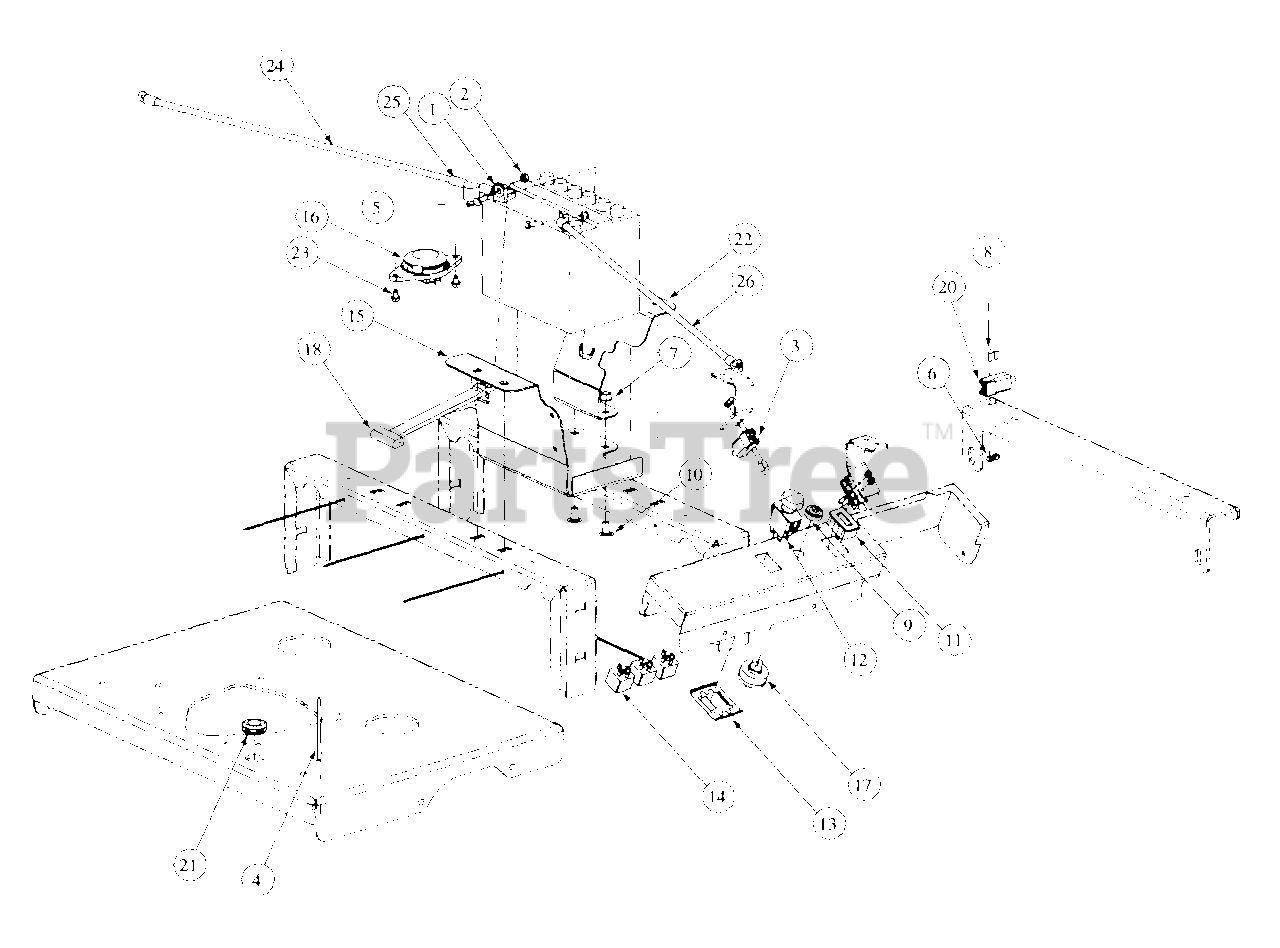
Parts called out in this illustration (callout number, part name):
1	Battery, 12V 225CCA 30 Min
2	Lock Nut, Nylon Insert, 1/4-20
3	Delta Switch
4	Cable Tie, 3/16 x .05 x 7.4
5	HHCS, 1/4-20, .75
6	Lock Nut, Nylon Insert, 10-32
7	Hex Nut, 3/8-16 Flange Lock
8	Phillips Head Screw, Machine, 10-32 x 5/8
9	Nut, W/Cap, 5/8-32 Ignition
10	Carriage Bolt, 3/8-16 x .75 Long
11	Hour Meter
12	Electric PTO Switch
13	Bracket, PTO Retainer Switch
14	Relay, 12V 40A
15	Mounting Bracket, Battery
16	Seat Switch
17	Ignition Switch, 6 Pin
18	Battery Strap, 400
20	Plunger Switch
21	Grommet, .75 ID
22	Mount Bracket, Front Battery
23	Screw, TT, 1/4-20, .500, Hex Index Washer
24	Battery Cable Red, 24"
25	Boot, 1" OD Rubber, Battery-PST, Red
26	Cable, Battery Black, 24"
